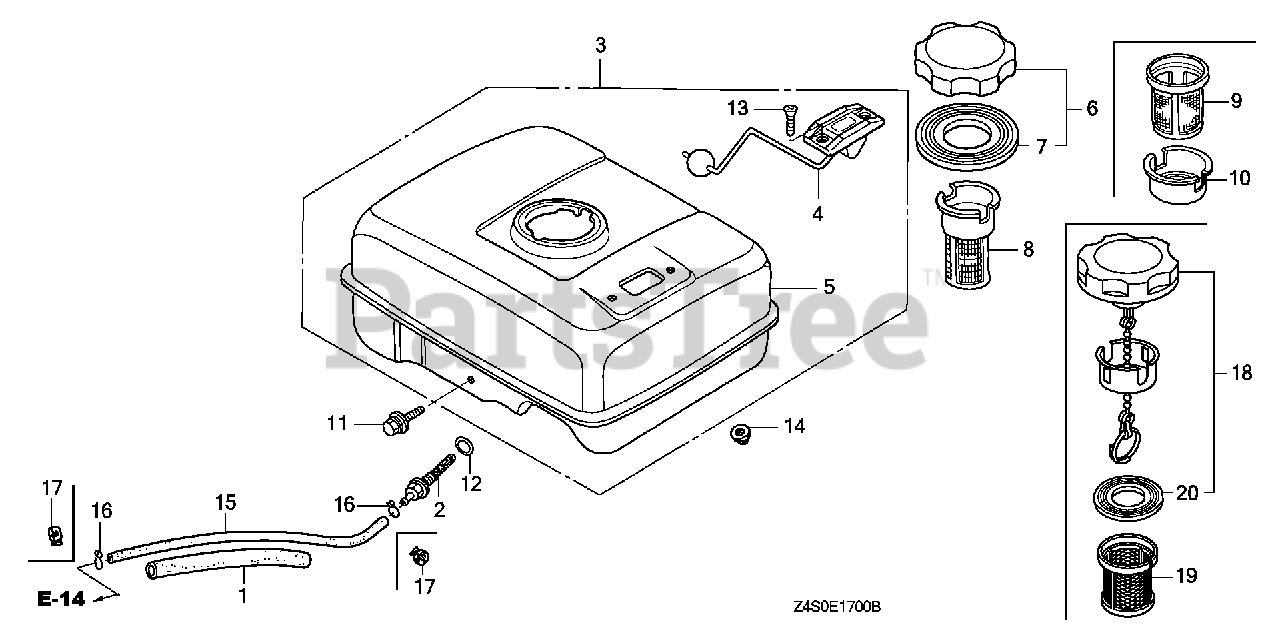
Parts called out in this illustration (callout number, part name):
1	RUBBER, SUPPORTER (107MM)
2	JOINT, FUEL TANK (NOT AVAILABLE)
2	JOINT, FUEL TANK
5	TANK, FUEL *NH31* (MCKINLEY WHITE) Use up to Engine SN 3033315.
6	CAP, FUEL FILLER (CHROME PLATED)
7	GASKET, FUEL FILLER CAP (39X62X3) (TOUYOUSYA)
11	BOLT, FLANGE (6X34)
12	O-RING (14MM) (ARAI) Use up to Engine SN 2949254.
12	O-RING (14MM) (NOK)
14	NUT, FLANGE (6MM)
15	TUBE, FUEL (4.5X140) (FKM)
15	BULK HOSE, FUEL (4.5X3000) (Honda Code 5137104). (4.5X140)
16	CLIP, TUBE (B8)
17	CLIP, TUBE (D8)
18	CAP, FUEL FILLER
20	GASKET, FUEL FILLER CAP
